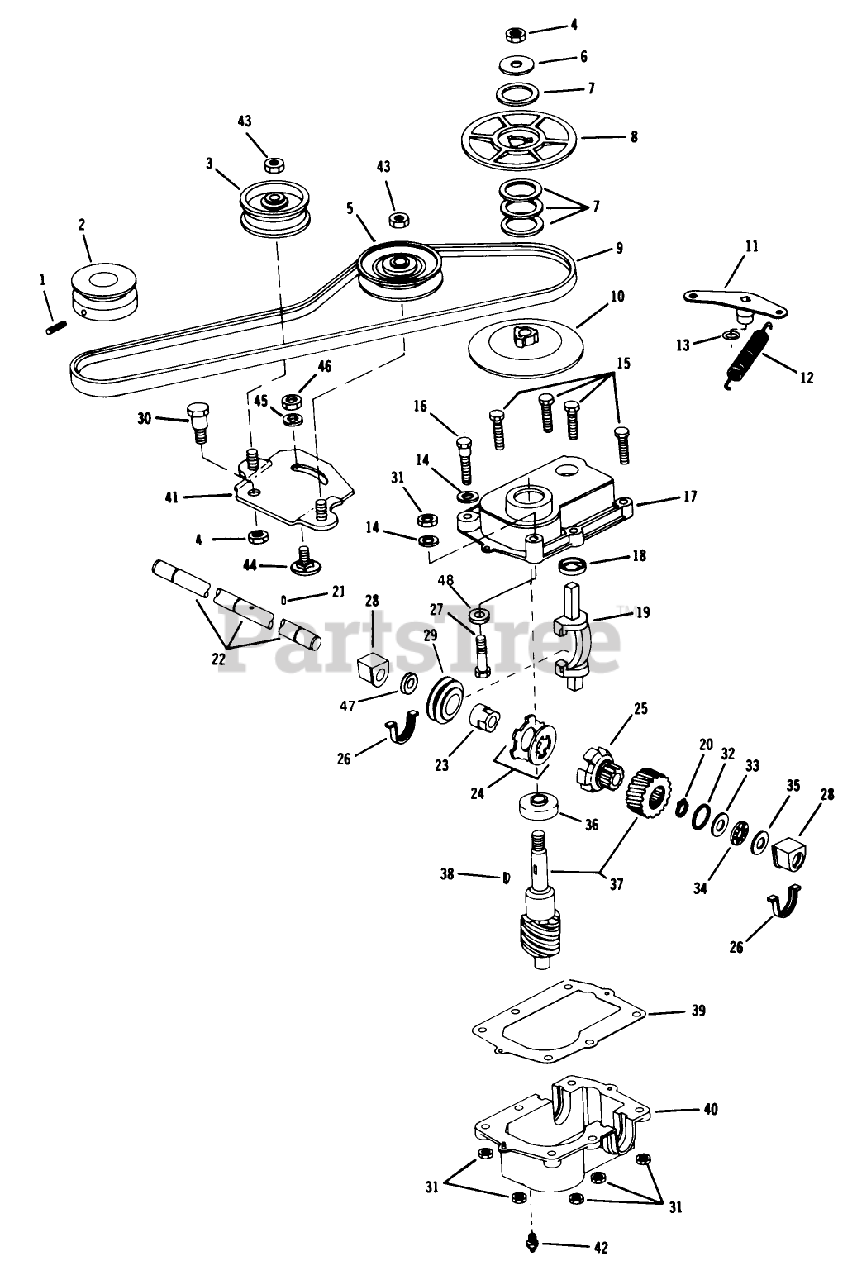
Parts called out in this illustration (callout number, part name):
1	SET SCREW F
2	PULLEY F
3	PULLEY NEWHAM IND *B
4	LOCKNUT
5	IDLER NEW HAM IND
6	WASHER
8	PULLEY UPPER PL
9	V-BELT
10	PULLEY LOWER PL
12	SPRING
13	O-RING
18	GUIDE ELCO
20	RET RING
21	PIN DRIVE LOCK
25	DRIVER BROCKWAY
28	BEARING & SEAL AY (12)
31	LOCKNUT E
33	WASHER-THRUST
35	THRUST WASHER
36	BEARING-BALL
38	KEY GALGER
39	GASKET HOOSIER
42	FITTING LINCOLN
43	NUT-JAM, LOCKING
45	WASHER M
46	NUT-LOCK F
47	WASHER
